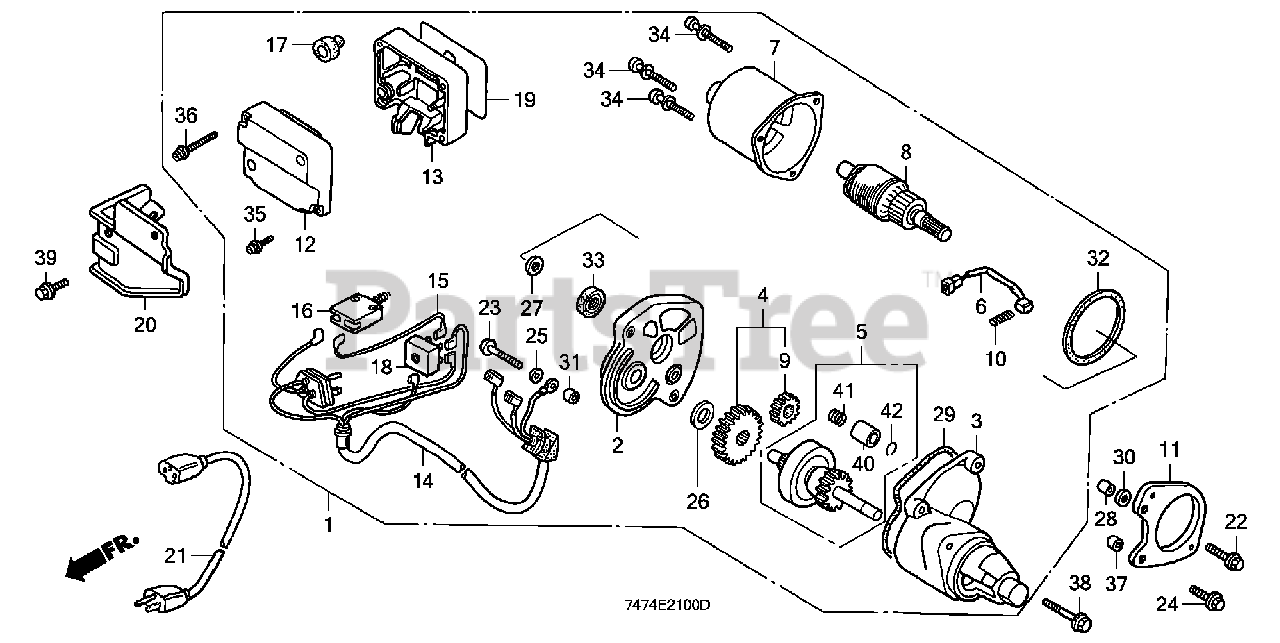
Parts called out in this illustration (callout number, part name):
1	MOTOR ASSY., STARTER
2	HOUSING, CENTER
3	HOUSING, PINION
4	GEAR, REDUCTION
9	GEAR, DRIVE
10	SPRING, BRUSH RETURN
11	BRACKET, STARTER MOTOR
16	SWITCH, STARTER (A.C. 380V-16A)
16	SWITCH, STARTER (A.C. 250V-16A)
19	PLATE, CAUTION (ENGLISH)
20	BRACKET, SWITCH BOX
21	WIRE, POWER (NOT AVAILABLE)
22	BOLT, FLANGE (6X32)
23	SCREW, TRUSS (4X30)
24	BOLT, FLANGE (6X25)
25	WASHER, STAR (4MM)
26	WASHER (A)
27	WASHER (B)
28	PIN, DOWEL (8X19)
30	COLLAR (8X5)
34	SCREW-WASHER (5X30)
35	SCREW-WASHER (4X20)
36	SCREW-WASHER (4X30)
37	PIN A, DOWEL (8X14)
38	BOLT, FLANGE (6X20)
39	BOLT, FLANGE (6X40)
40	STOPPER, PINION
41	SPRING, COIL
42	RING, RETAINING
